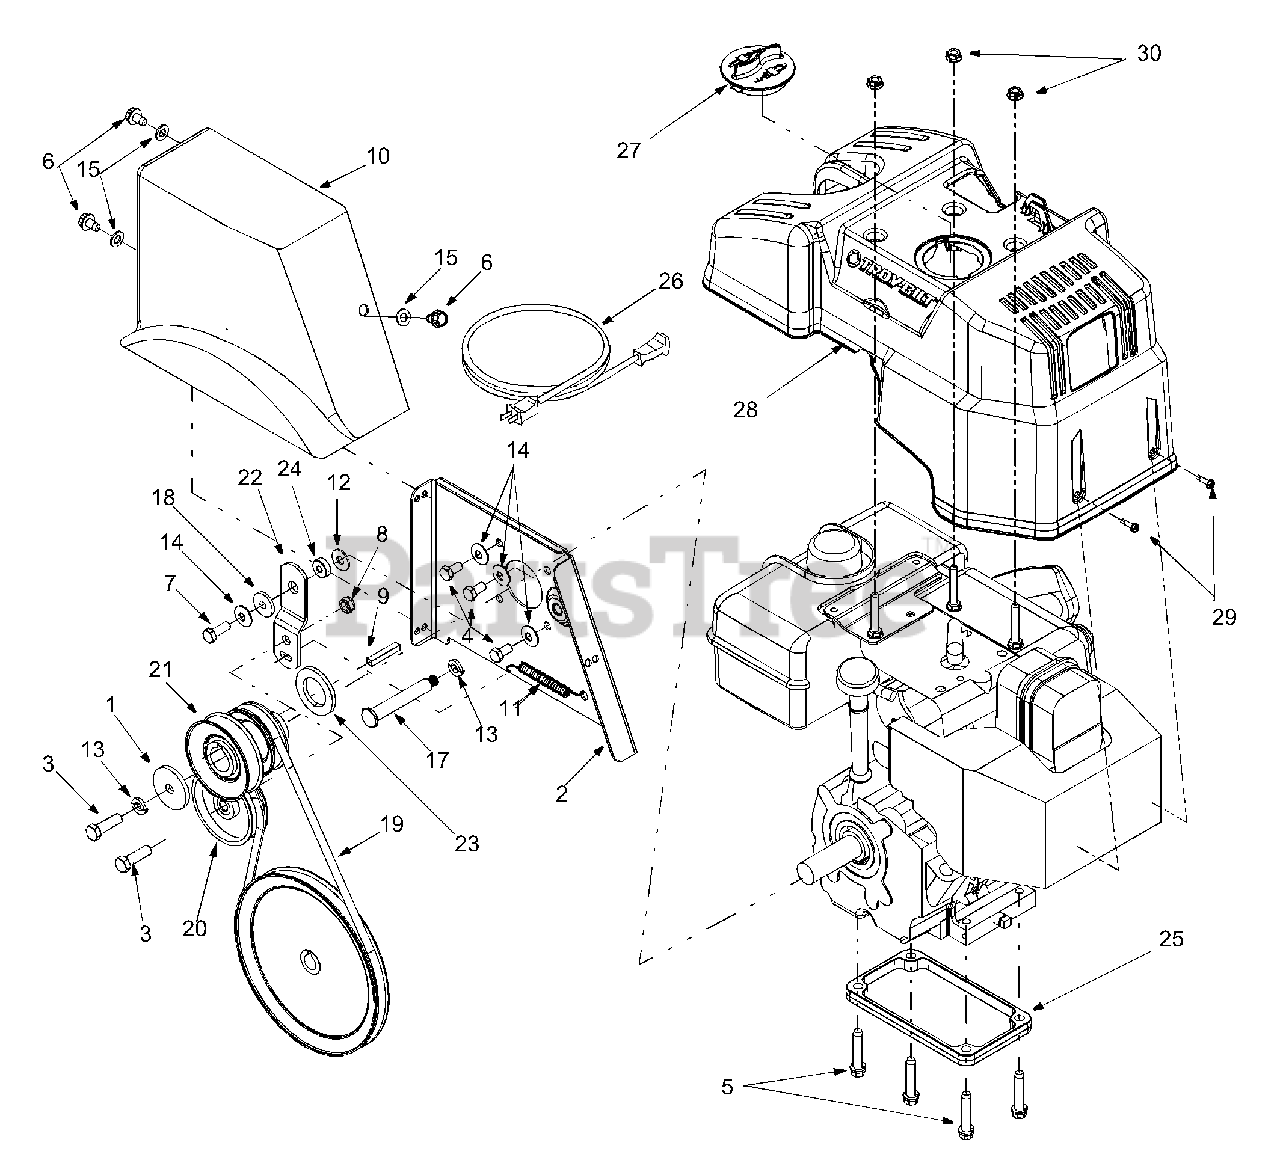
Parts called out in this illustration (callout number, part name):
4	Hex Screw 5/16-24 x .625"
5	Self-tapping Sems Screw
6	TT Screw 5/16-18 x 0.5"
7	Hex Lock Screw 5/16-24 x 1.25"
10	Belt Cover
11	Extension Spring
12	5/16 Washer
13	Lock Washer
14	Beleville Washer
15	Flat Washer
17	Shoulder Screw
18	Shoulder Spacer
19	V-Belt
20	Flat Idler
21	Double Pulley
22	Idler Bracket
24	Spacer, .33 x 1.0 x .36
26	Extension Cord: 110V, 3-prong
27	Spark Plug Cap
28	Engine Shroud
29	Screw, #10-16 x .75
30	Flange Lock Nut, 5/16-18
